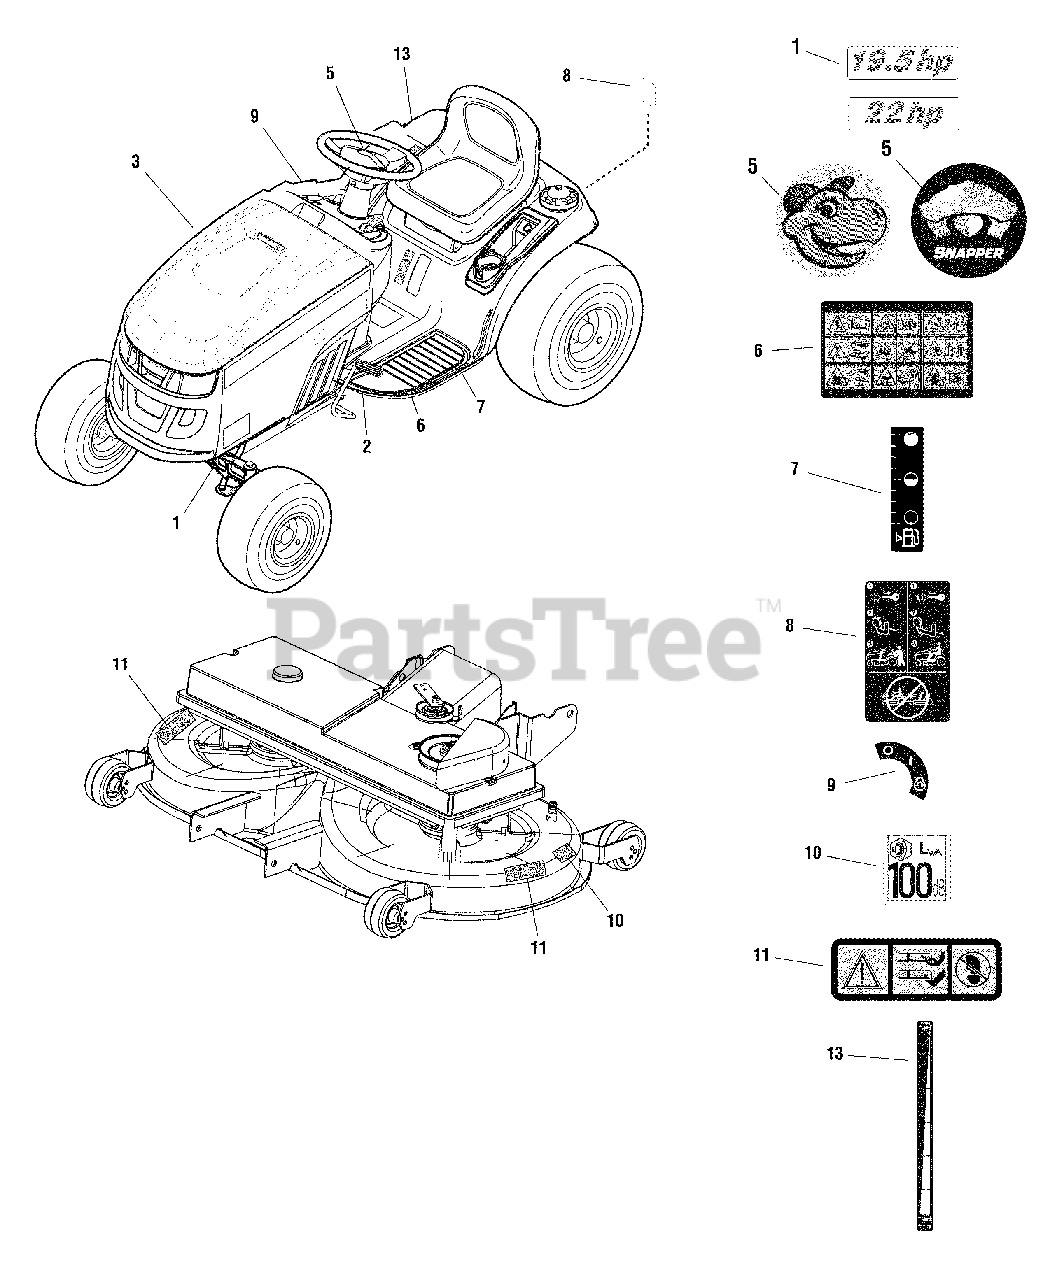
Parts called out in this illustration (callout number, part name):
1	DECAL, 19.5HP
1	DECAL, 22HP
2	DECAL, Snapper LH Stripe
3	DECAL, Snapper RH Stripe
5	DECAL, Snapper Steering Wheel
6	DECAL, Tunnel
7	DECAL, Fuel level
8	DECAL, Trans/Tow Release Lever
9	DECAL, Ignition Switch White/Blk
10	DECAL, Noise
11	DECAL, Safety
13	DECAL, Mower Height
